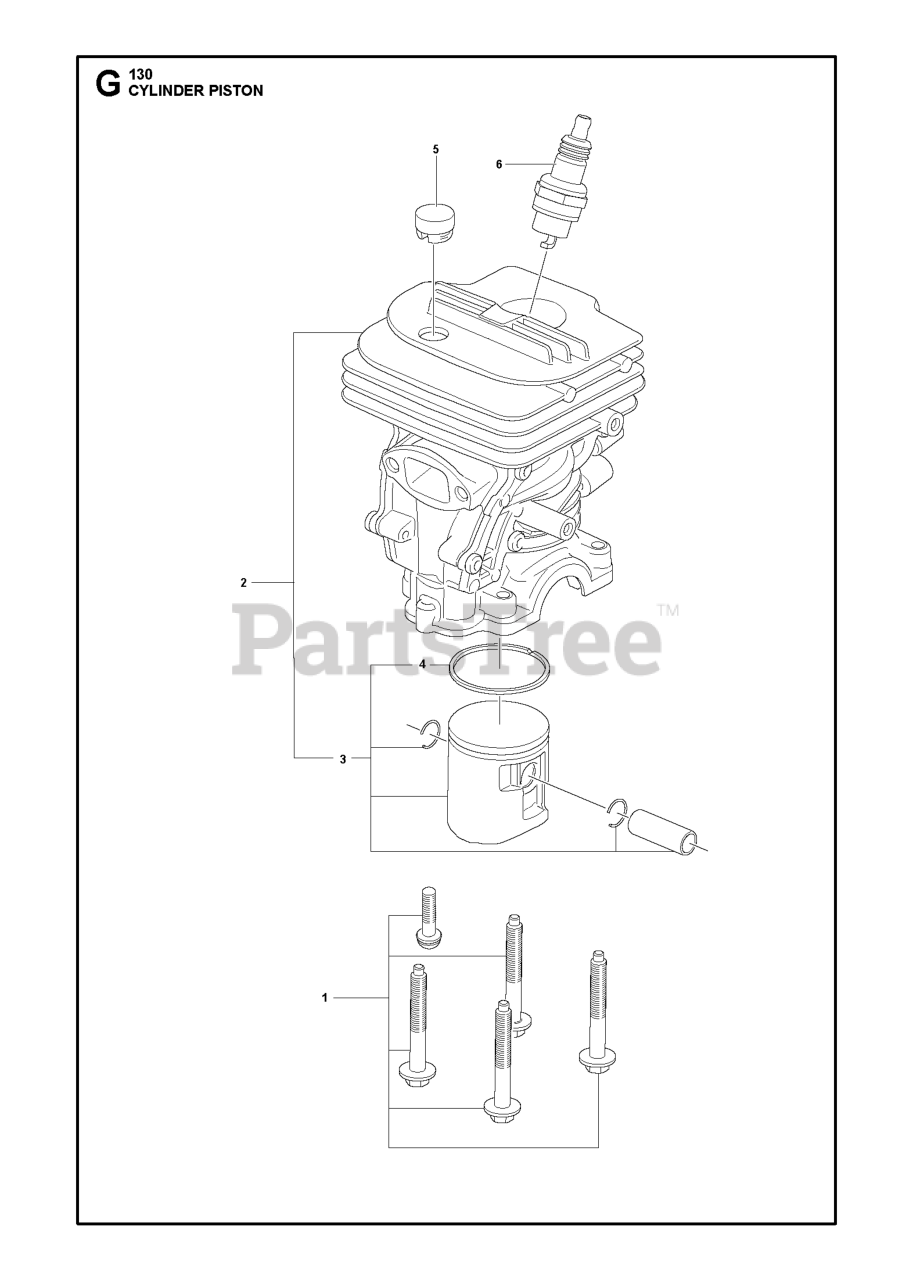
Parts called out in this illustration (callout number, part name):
1	SERVICE KIT CYLINDER BOLT
2	SERVICE KIT CYLINDER AND PISTO
3	SERVICE KIT PISTON ASSEMBLY
4	PISTON RING 38CC
5	SUPPORT CYLINDER COVER
6	SPARK PLUG M14X1.25 NGK BPMR7A
